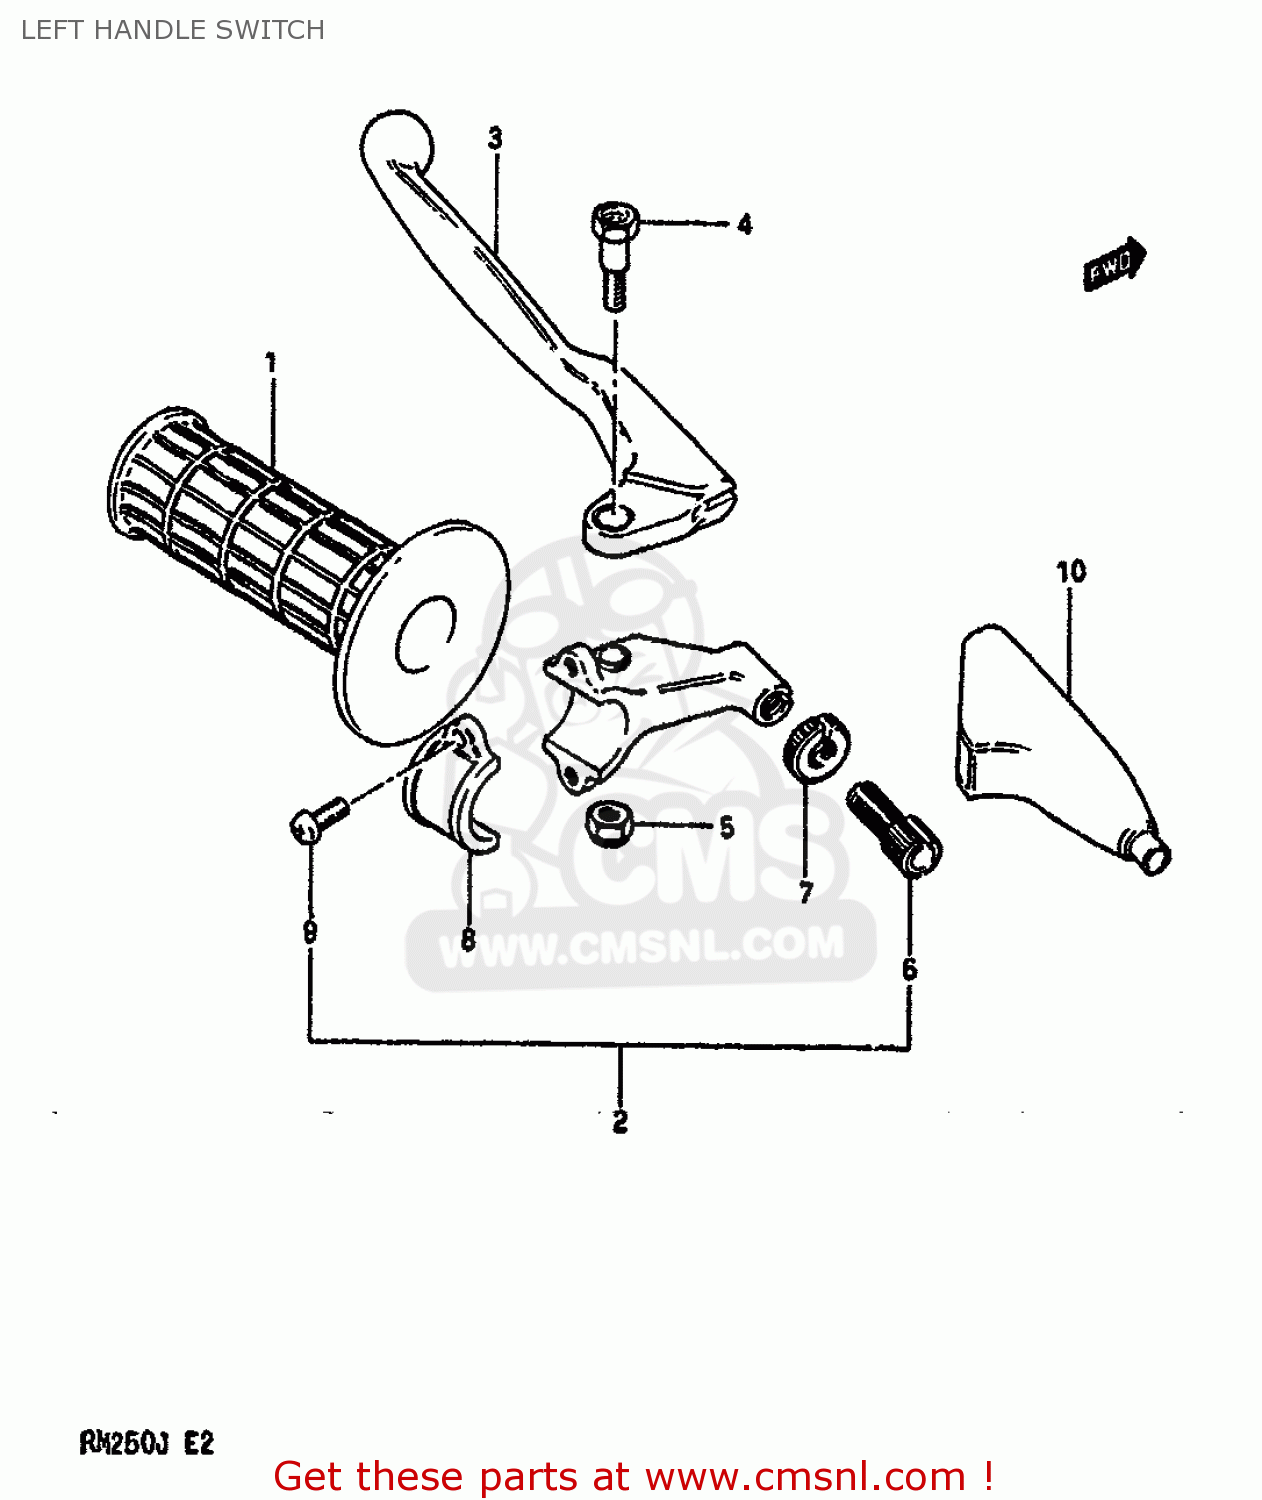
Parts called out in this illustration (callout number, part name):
1	GRIP,LEFT
2	LEVER ASSEMBLY
3	LEVER,CLUTCH
4	BOLT,LEVER
5	NUT
6	ADJUSTER,CABLE
7	NUT,CABLE ADJUSTER LOCK
8	HOLDER,LEVER
9	SCREW (5X14)
10	COVER,CLUTCH LEVER
